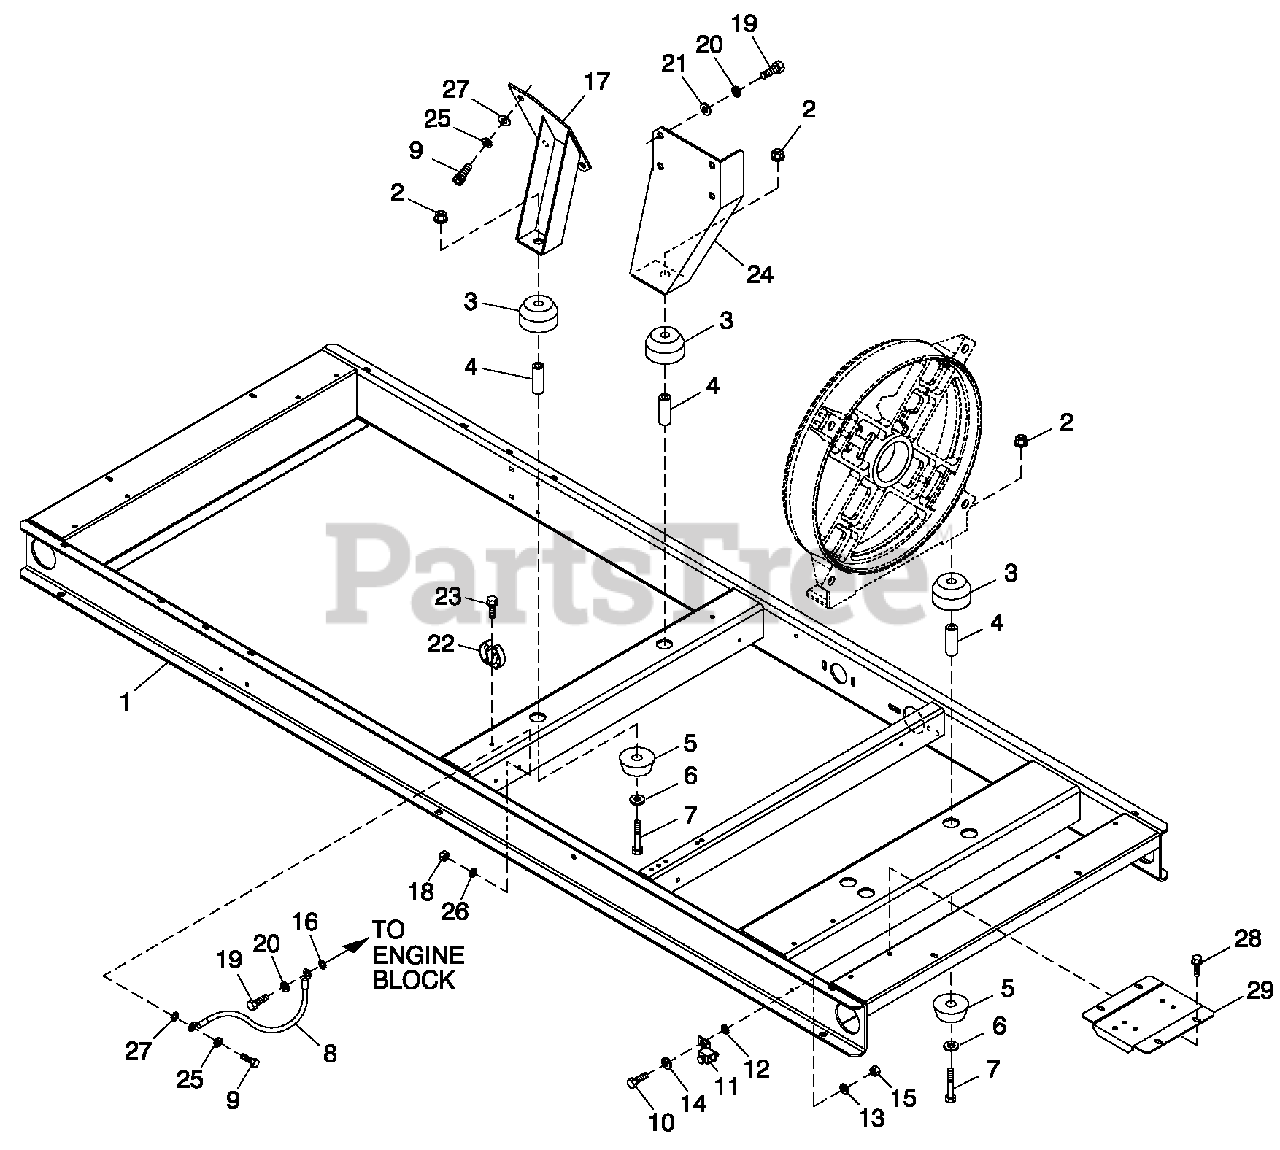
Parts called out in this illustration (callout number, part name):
1	MOUNTING BASE 60KW C4
2	NUT FLANGED HEX M12-175
3	DAMPENER VIBRATION 40 BLUE
4	SPACER.49 X .62 X 1.87 PWDR/ZNC
5	DAMPENER VIBRATION
6	WASHER FLAT M12
7	SCREW HHC M12-1.75 X 80 G8. 8
8	ASSY WIRE 14. 00"
9	SCREW SHC M8-1.25 X 30 G12 . 9
10	SCREW HHC M6-1.0X 16 G8. 8
11	LUG SLDLSS #2-#8X 17/64 CU
12	WASHER SHAKEPROOFINT 1/4
13	WASHER LOCK M6-1/4
14	WASHER FLAT M6-1/4 ZINC
15	NUT HEX M6 -1.0 G8YEL CHR
16	WASHER SHAKEPROOF EXT 7/16 STL
17	SUPPORT ENGINE LH
18	NUT HEX M8-1.25 G8 CLEAR ZINC
19	SCREW HHC M10-1. 5X25G8 .8
20	WASHER LOCK 7/16
21	WASHER FLAT 3/8-M10 ZINC
22	SPRING CLIP HOLDER .37- .62
23	SCREW HHTT M4-0. 7X 8 BP
24	SUPPORT ENGINE RH
25	WASHER LOCK M8-5/16
26	WASHER SHAKEPROOF INT 5/16
27	WASHER FLAT 5/16-M8 ZINC
28	SCREW THF M6-1 X 16 N WA Z/JS
29	SUPPORT CONTROL PANEL CPL C4
